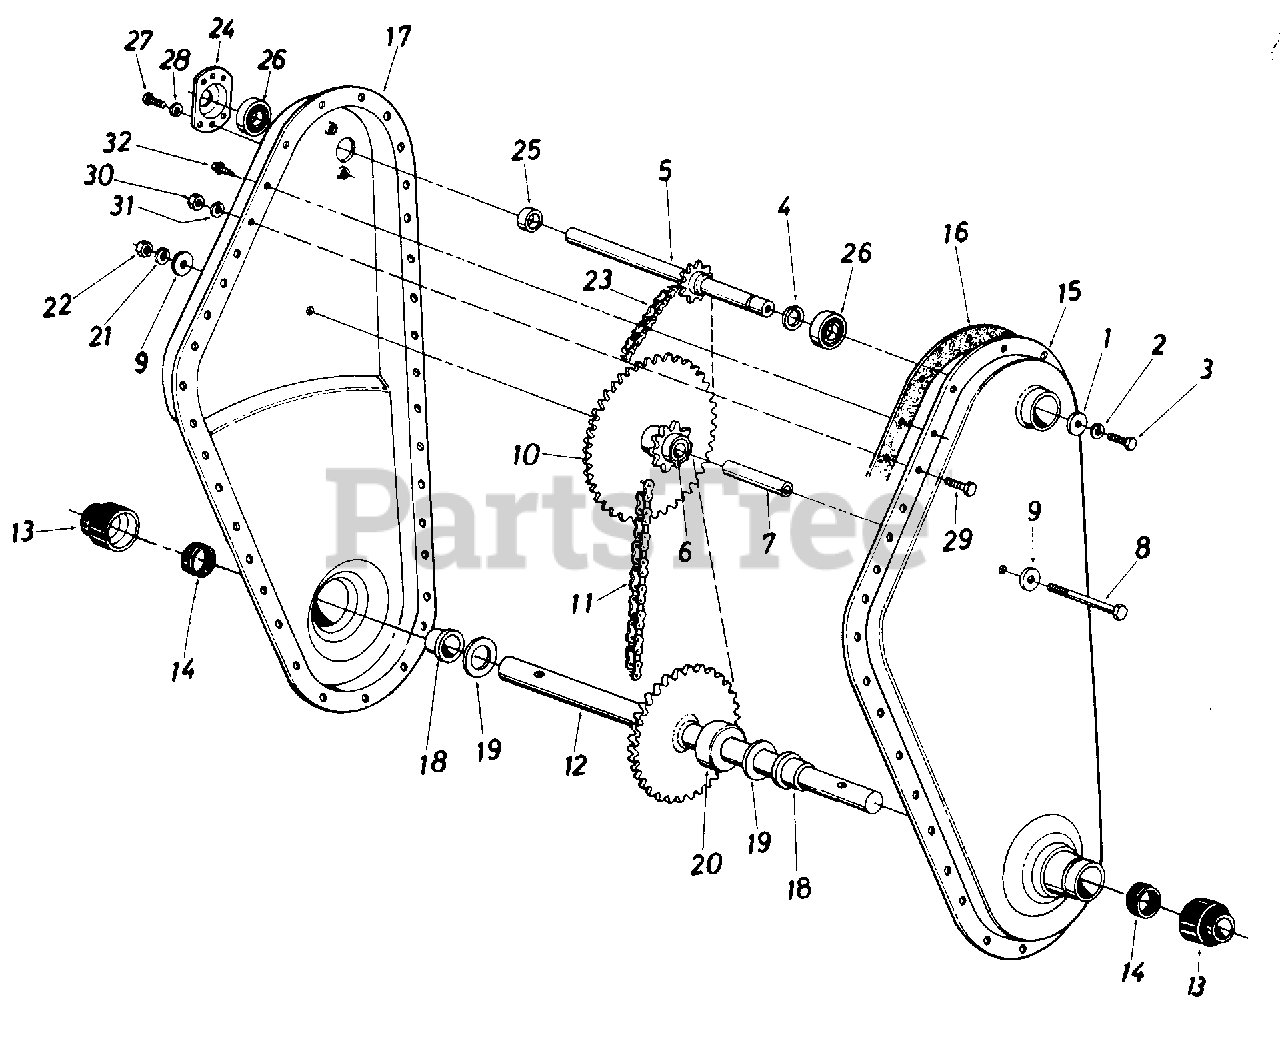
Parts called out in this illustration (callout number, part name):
1	Fl-Wash. 1/4" I.D. x .93" O.D. x .120
2	L-Wash. 1/4" I.D.
3	Hex Bolt 1/4-28 x .62" Lg. w/Patch
4	External Snap Ring-5/8" Dia.
5	Input Shaft Ass'y.
6	Bearing 518" I.D. x 3/4" O.D. x 1.860" Lg.
7	Sprocket Hub Tubing 3/8" I.D. x 518" O.D. x 1.90
8	Hex Bolt 3/8-24 x 2.75" Lg.
9	Fl-Wash. 3/8" I.D. x 1.25" O.D. x .10
10	Sprocket Ass'y.
11	#50 Chain 518" Pitch x 46 Links Endless
12	Tine Shaft Ass'y.
13	Dust Cup
14	Seal Ring Single Lip, Springless
19	Fl-Thrust Wash. 1.0" I.D. x .03 Thk.
20	Step Spacer
21	L-Wash. 3/8" I.D.
22	Hex Nut 3/8-24 Thd.
23	#35 Chain 3/8" Pitch x 52 Links Endless
24	Bearing Housing 1.38" I.D.
25	Spacer
26	Ball Bearing .625" I.D. x 1.38" O.D. x .437
27	Hex Wash. SF-Tap Scr. 1/4-20 x .50" Lg.
28	L-Wash. 1/4" I.D.
29	Hex Bolt 5/16-18 x .75" Lg.
30	Hex Nut 5/16-18 Thd.
31	L-Wash. 5/16" I.D.
32	Hex Wash. SF-Tap Scr. 1/4-20 x .50" Lg.
